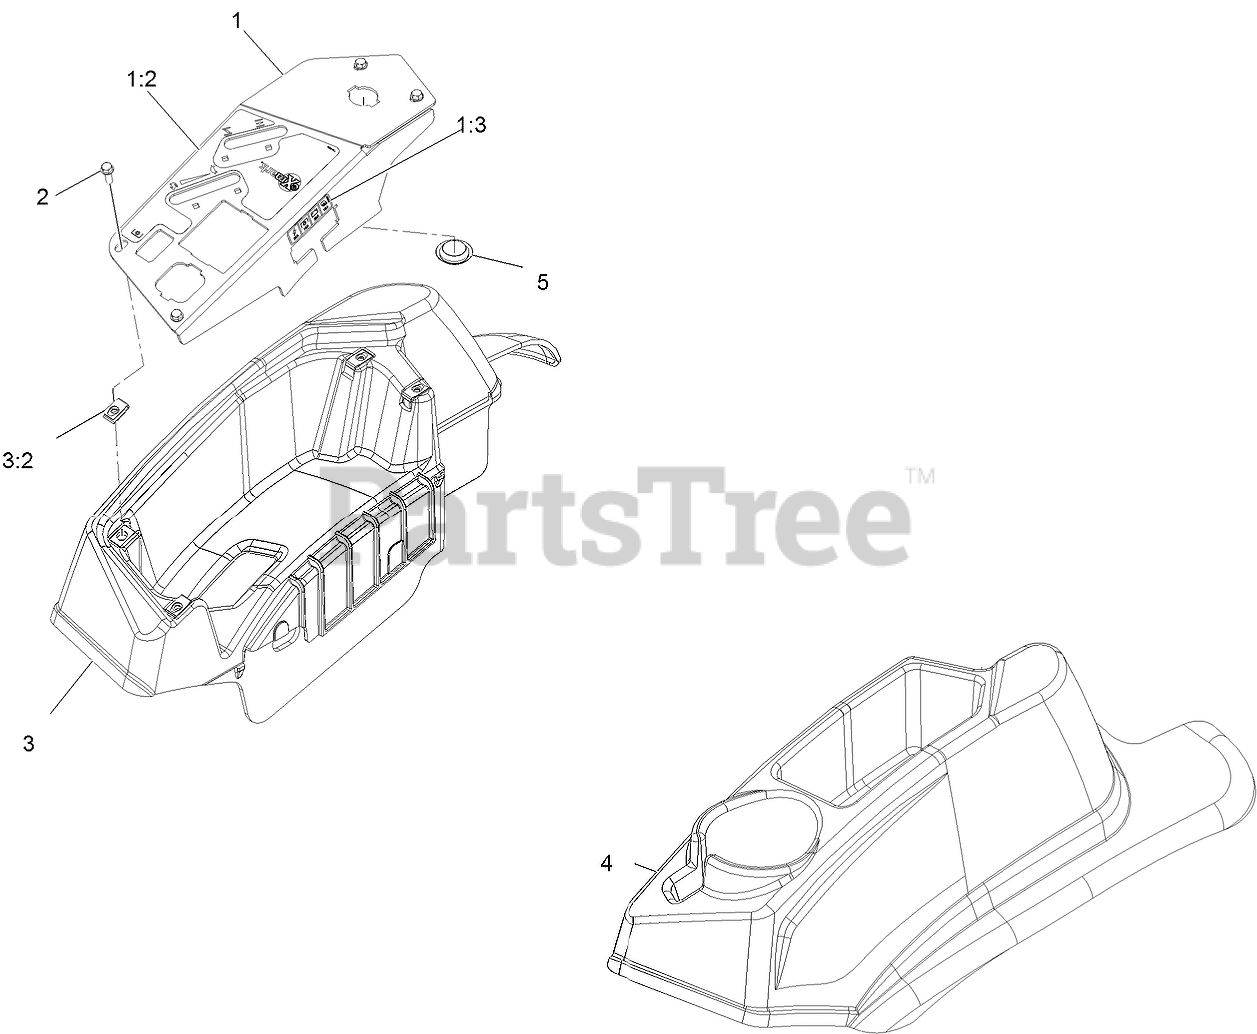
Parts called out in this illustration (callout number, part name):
1	ASM-PANEL, CONTROL W/DECAL
1:2	DECAL-CONTROL PANEL NON-EFI
1:3	DECAL-FUSES
2	SCREW-HWH
3	CONSOLE,RH AS ASM
4	CONSOLE, LH AS
5	PLUG-PLASTIC
